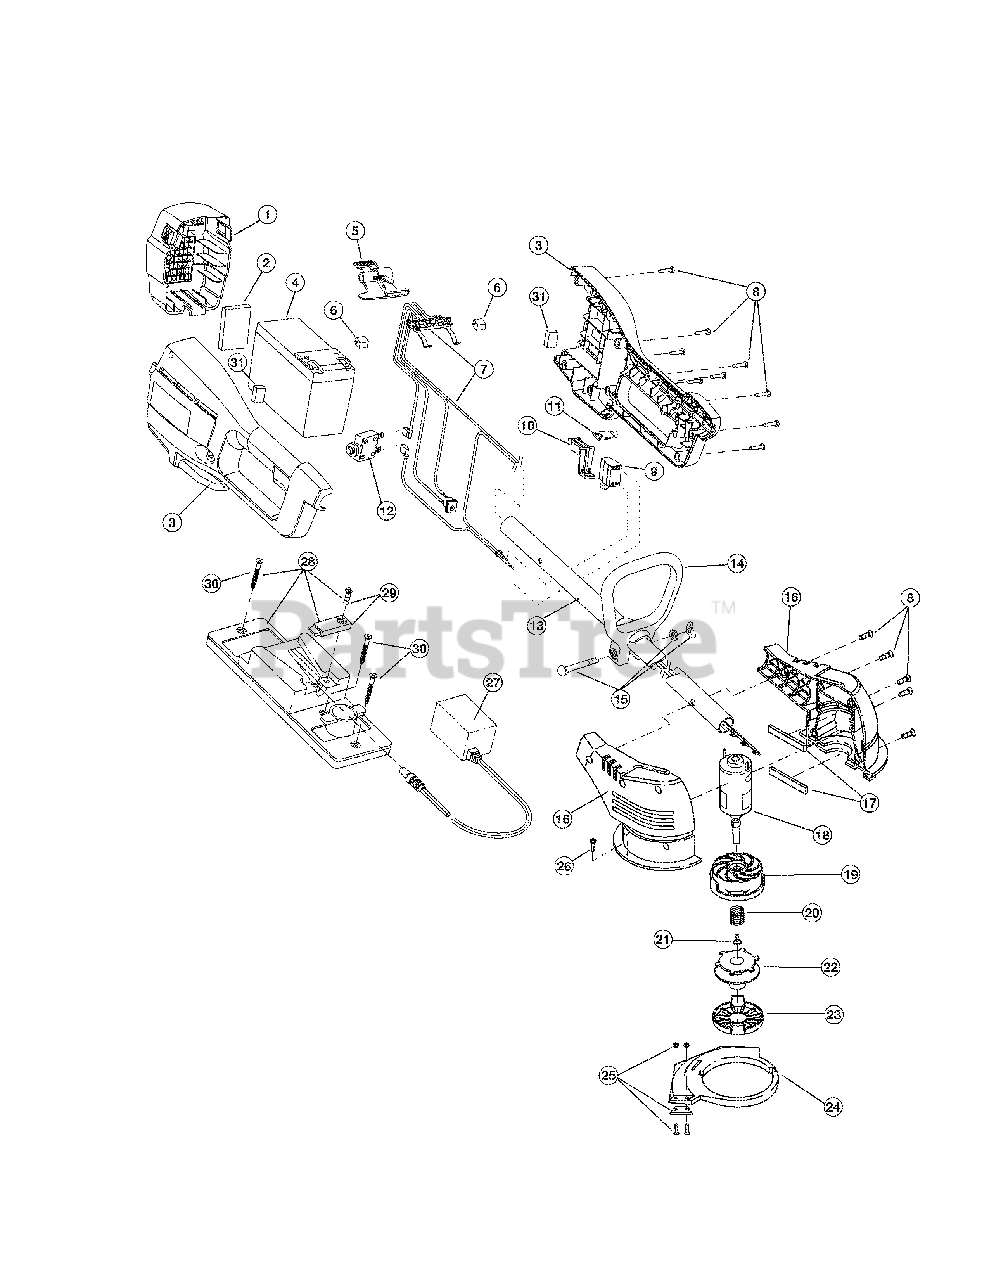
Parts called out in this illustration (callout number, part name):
1	Battery Door
2	Foam Pad
3	Battery Housing
4	12 Volt Batterry
5	Battery Latch
6	Terminal Spacer
7	Wiring Harness Assembly
8	Housing Screw
9	Switch Assembly (includes 10)
10	Trigger
11	Lock-Off Button
12	Circuit Breaker
13	Motor Wire Tube
14	D-Handle (includes 15)
15	Handle Hardware
16	Motor Housing
18	Motor with Shaft
19	Outer Spool and Eyelet/Motor Fan
22	Inner Reel with .080" Line
23	Reel Cover
24	Guard Assembly (includes 25)
25	Blade Assembly
26	Guard Screw
27	12 Volt Charger
28	Charging Station Stand (includes 29 & 30
29	Barrel Clamp with Screw
30	Mounting Screw
31	Front Battery Pads
